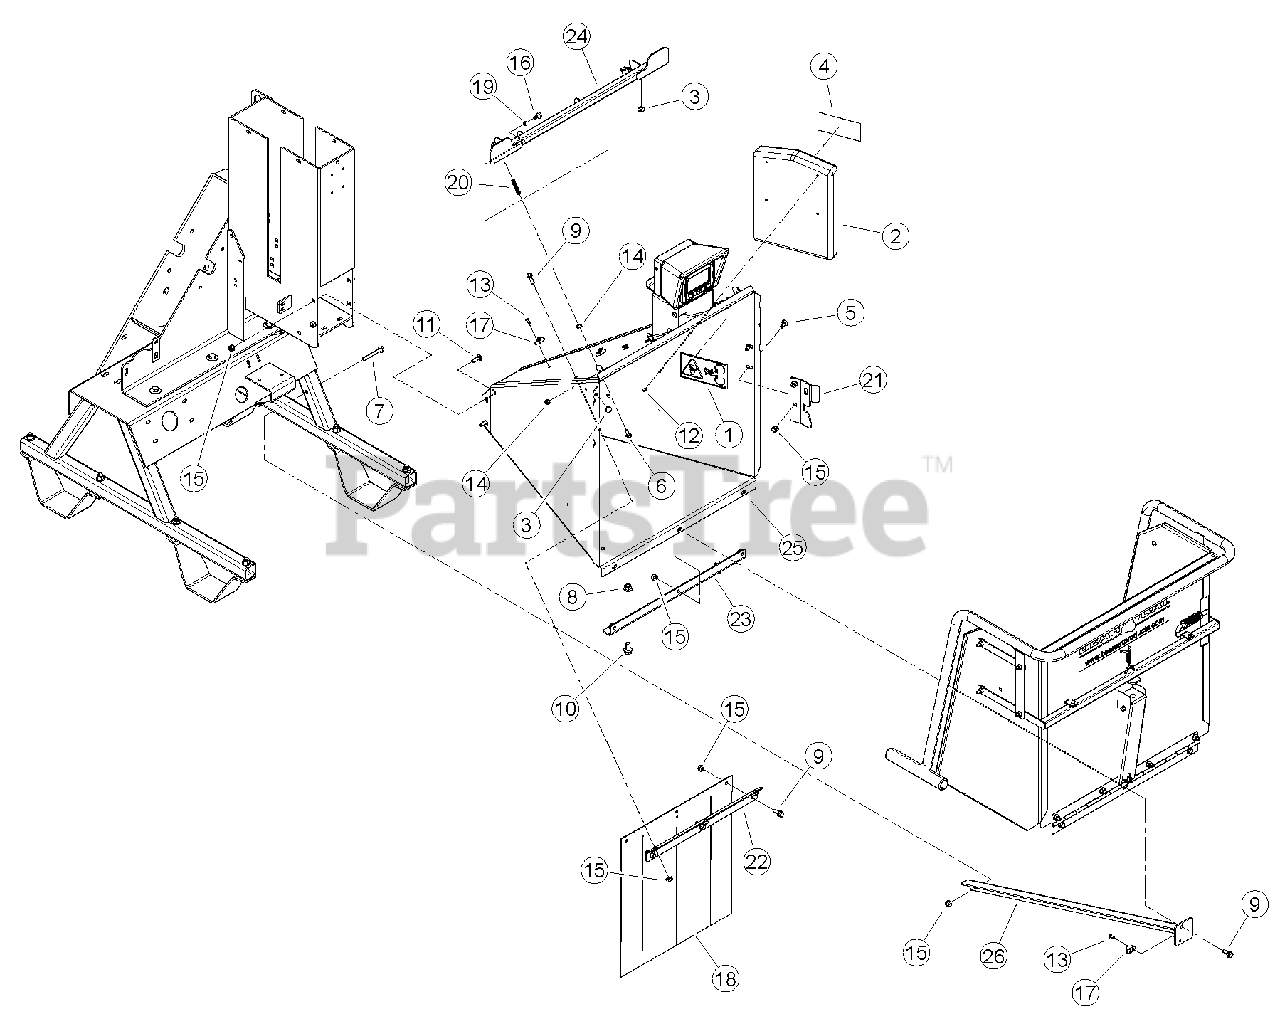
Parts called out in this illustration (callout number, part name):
1	DECAL, BLADE DANGER ISO
2	CONTAINER, INSTR. MANUAL
3	BUMPER, RUBBER
4	DECAL, MUTILINGUAL MANUAL
5	BOLT, 3/8 X 1" GR5 CRG NC ZP
6	BOLT, 5/16 X 3/4 FLANGE NC
7	BOLT, 3/8 X 3 FLANGE NC
8	NUT, 1/2-13 NYLOCK FLANGE
9	BOLT, 3/8 X 1 FLANGE NC
10	BOLT, 1/2-13 1.00 GR5 FLANGE NC
11	BOLT, 3/8 X 1-1/4" GR5 CRG NC ZP
12	RIVET, AL BLIND 1/4 X 1/2 DOME HEAD
13	RIVET, AL BLIND 1/4 X 3/4 DOME HEAD
14	NUT, 5/16-18 NYLOCK-FLANGE
15	NUT, 3/8-16 NYLOCK FLANGE
16	BOLT, 5/16-18 X 3/4 ZP FLANGE SHOULDER
17	CLAMP, CABLE MOUNT
18	FLAP, 5 INCH CHUTE
19	BEARING, .375 X .50 X .25 LONG
20	SPRING, COMPRESSION .437 DIA X 2.0 LONG
21	PLATE, TRAY LATCH
22	SUPPORT, 5 INCH CHIPPER FLAP
23	ANGLE, 5" INFEED SUPPORT
24	WELDMENT, 5" TOP SAFETY BAR
25	WELDMENT, 5" CHIPPER CHUTE
26	WELDMENT, CHUTE SUPPORT
